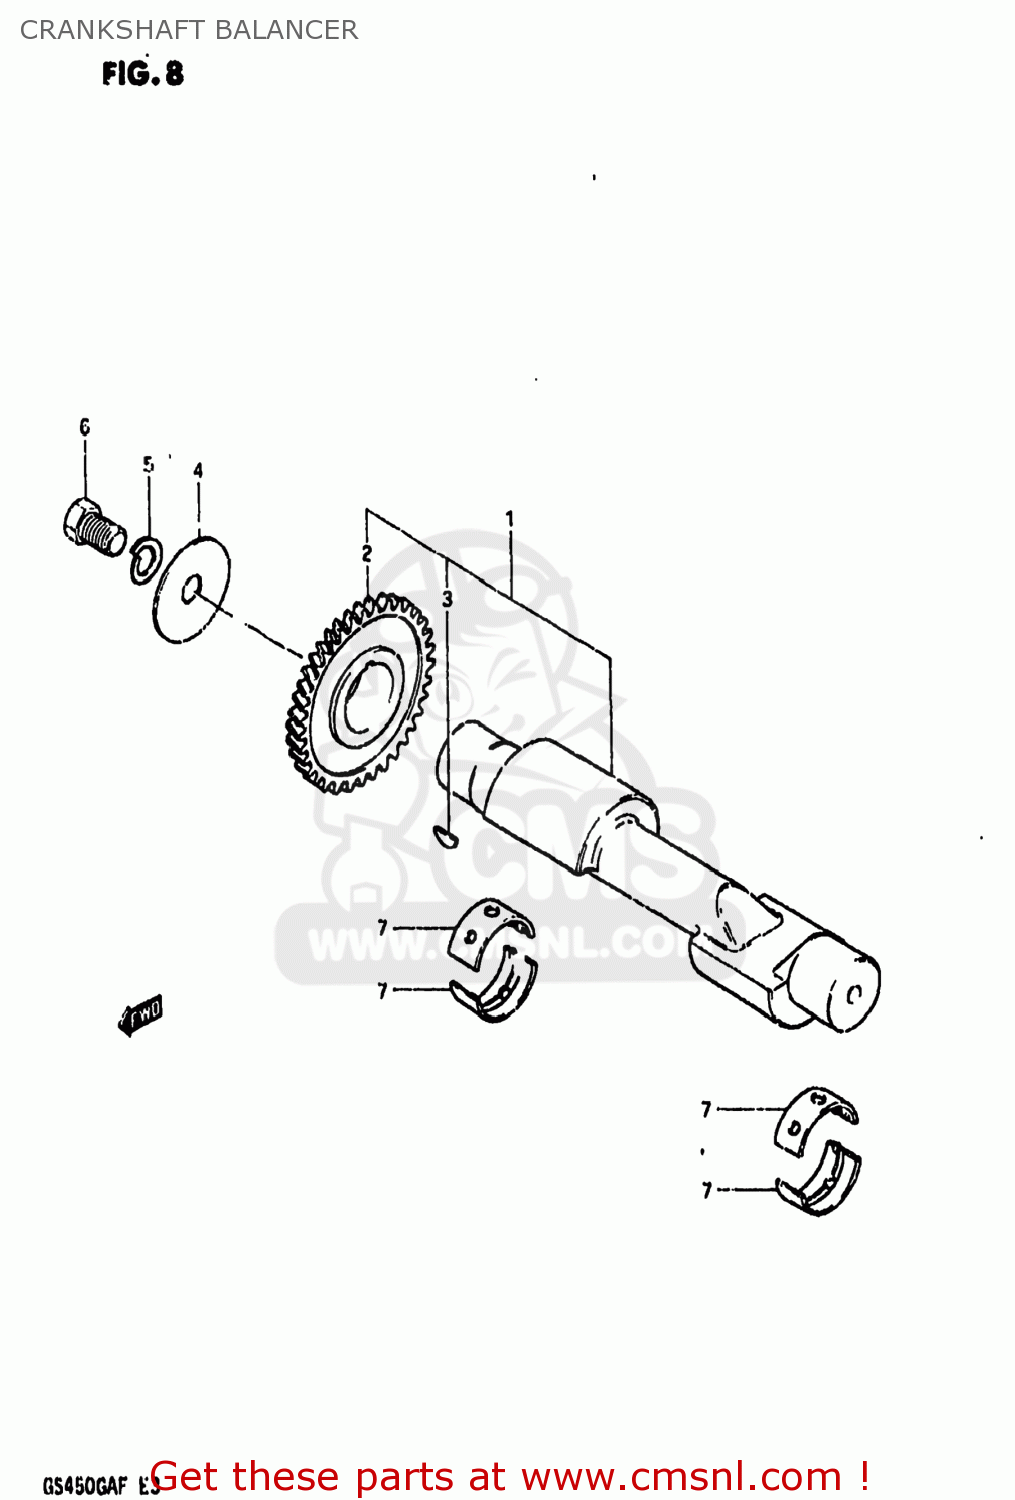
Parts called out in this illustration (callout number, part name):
1	BALANCER,CRANKSHAFT
2	GEAR,CRANK BALANCER
3	KEY 4MM
4	WASHER(12X50X3)
5	WASHER,LOCK 12
6	BOLT
7	METAL CRANKSHAFT
